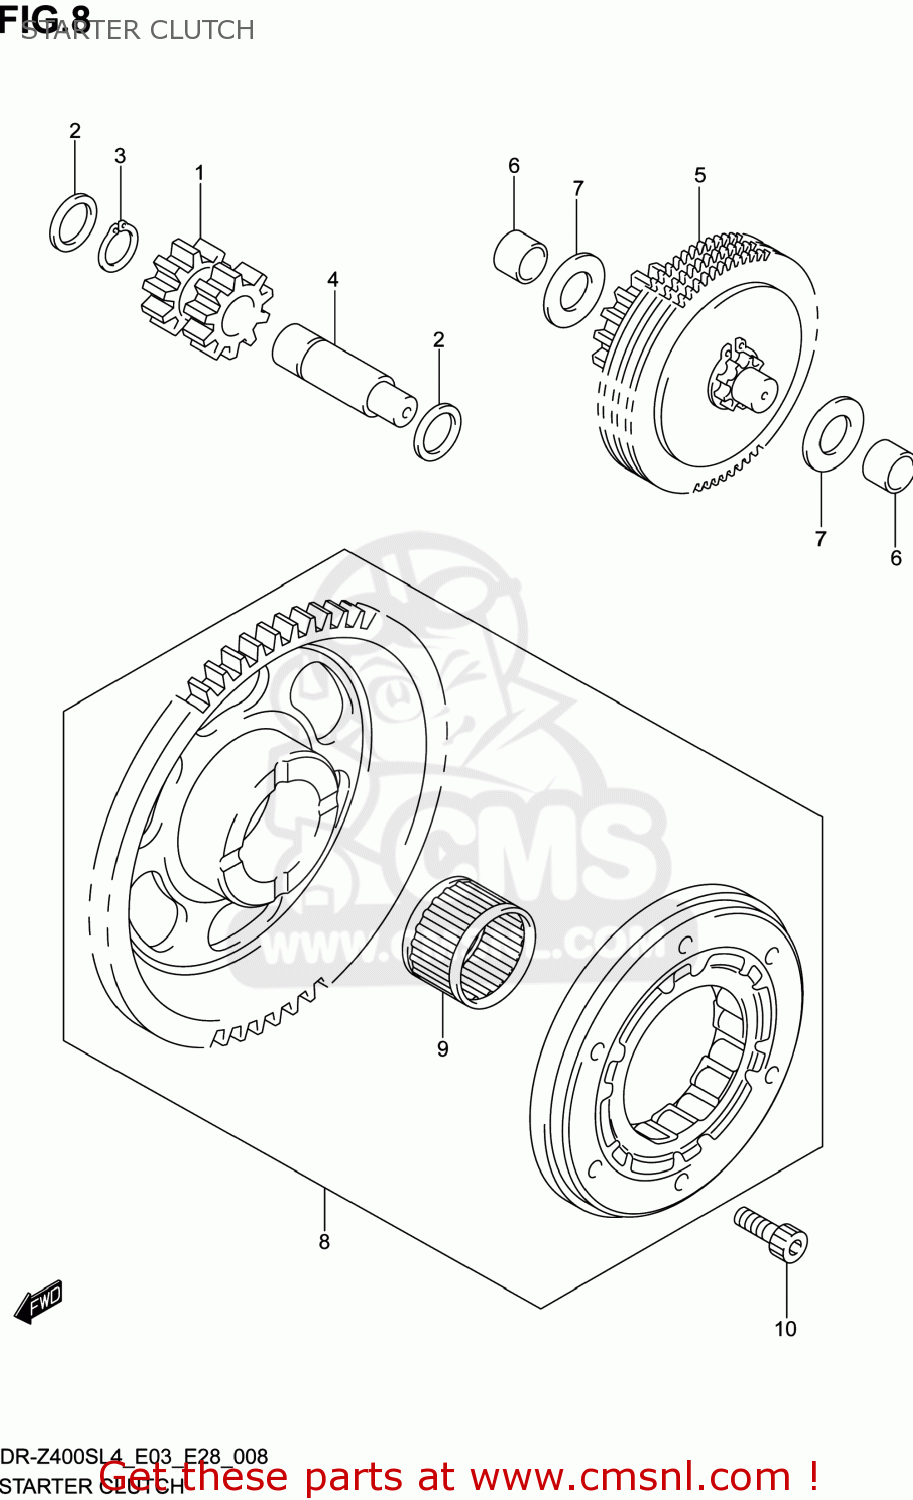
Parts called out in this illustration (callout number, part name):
1	GEAR,STARTER IDLE NO.1
2	SHIM(12X18X0.5)
3	CIRCLIP
4	PIN,STARTER IDLE GEAR NO.1
5	LIMITER ASSY,STARTER IDLE GEAR
6	BUSH,LIMITER GEAR SHAFT
7	WASHER
8	CLUTCH SET,STARTER
9	BEARING(25X31X19)
10	BOLT(6X16)
